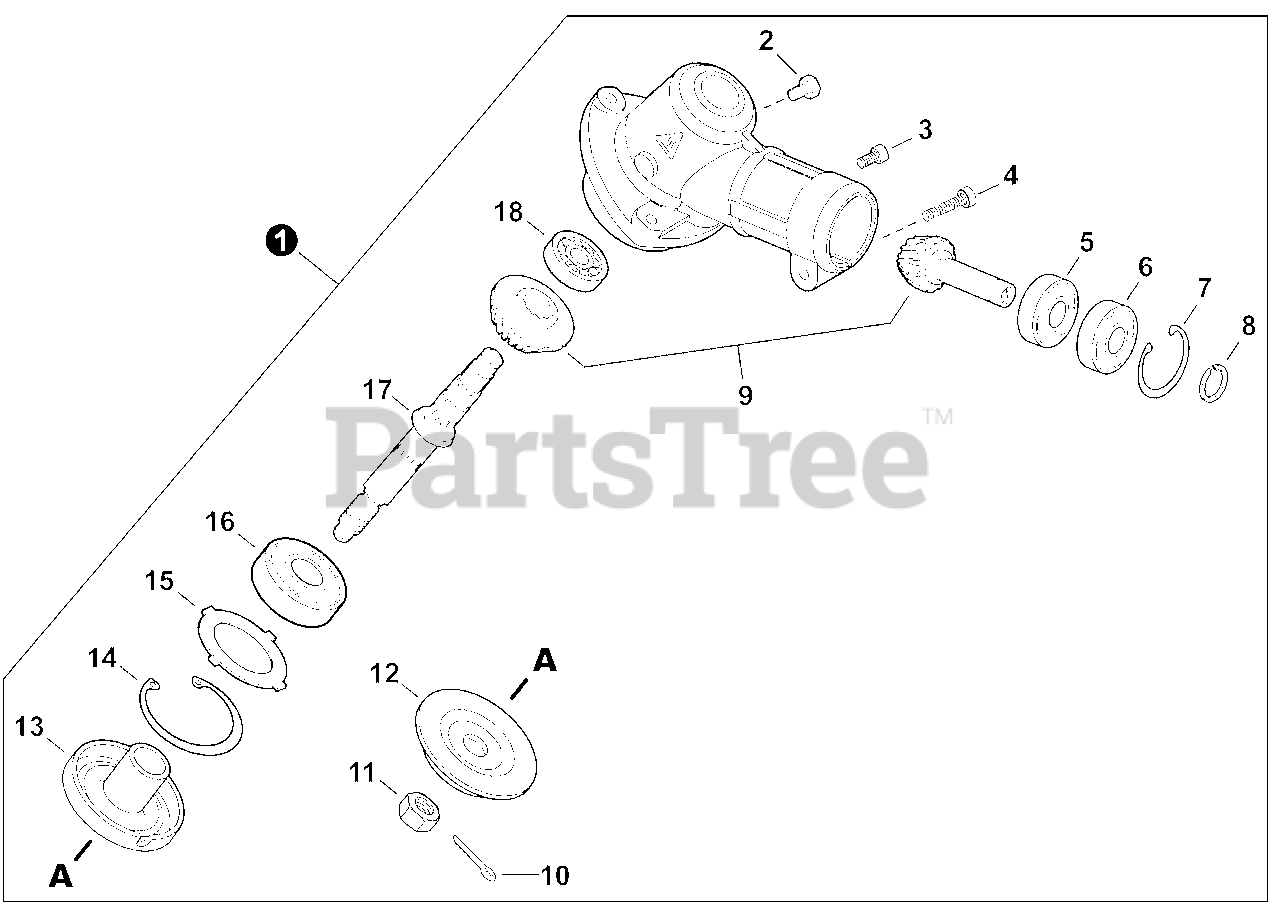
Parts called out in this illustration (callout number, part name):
1	GEAR CASE ASSY
2	BOLT M8×8
3	BOLT, TORX 5×10
4	BOLT, TORX 5×25
5	BEARING, BALL 609
6	BEARING, BALL 609
7	RING, SNAP Ø25
8	RING, SNAP Ø9
9	GEAR SET, BEVEL
10	PIN, COTTER 2×22
12	PLATE, ADAPTOR - LOWER
13	PLATE, ADAPTOR - UPPER
14	RING, SNAP Ø32
16	BEARING, BALL 6201
17	SHAFT, GEAR
18	BEARING, BALL 629
